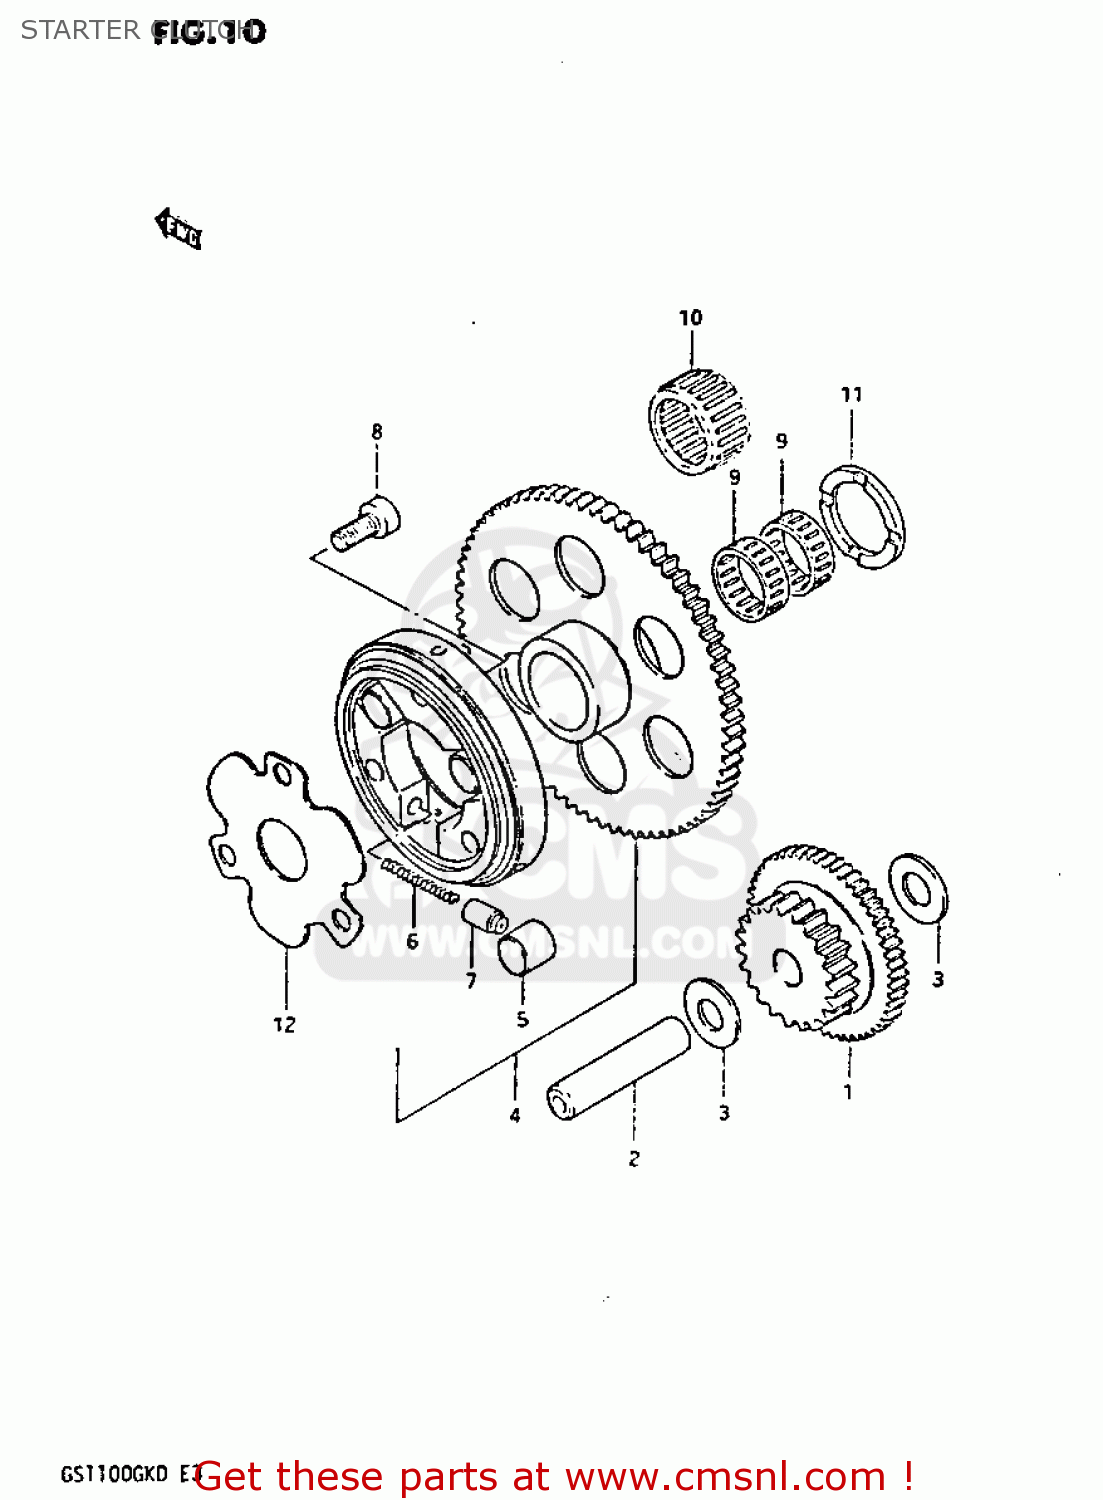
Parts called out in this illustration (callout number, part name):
1	GEAR,STARTER IDLE
2	PIN(7.4X13X56)
3	WASHER(13.3X25X0.85)
4	CLUTCH SET,STARTER
5	PIN(14X13)
6	SPRING
7	PIECE,PUSH
8	BOLT
9	ROLLER BEARING (25X31X2
10	ROLLER BEARING (25X31X2
11	WASHER(25X38X2.5)
12	SHIM,STARTER CLUTCH HUB
